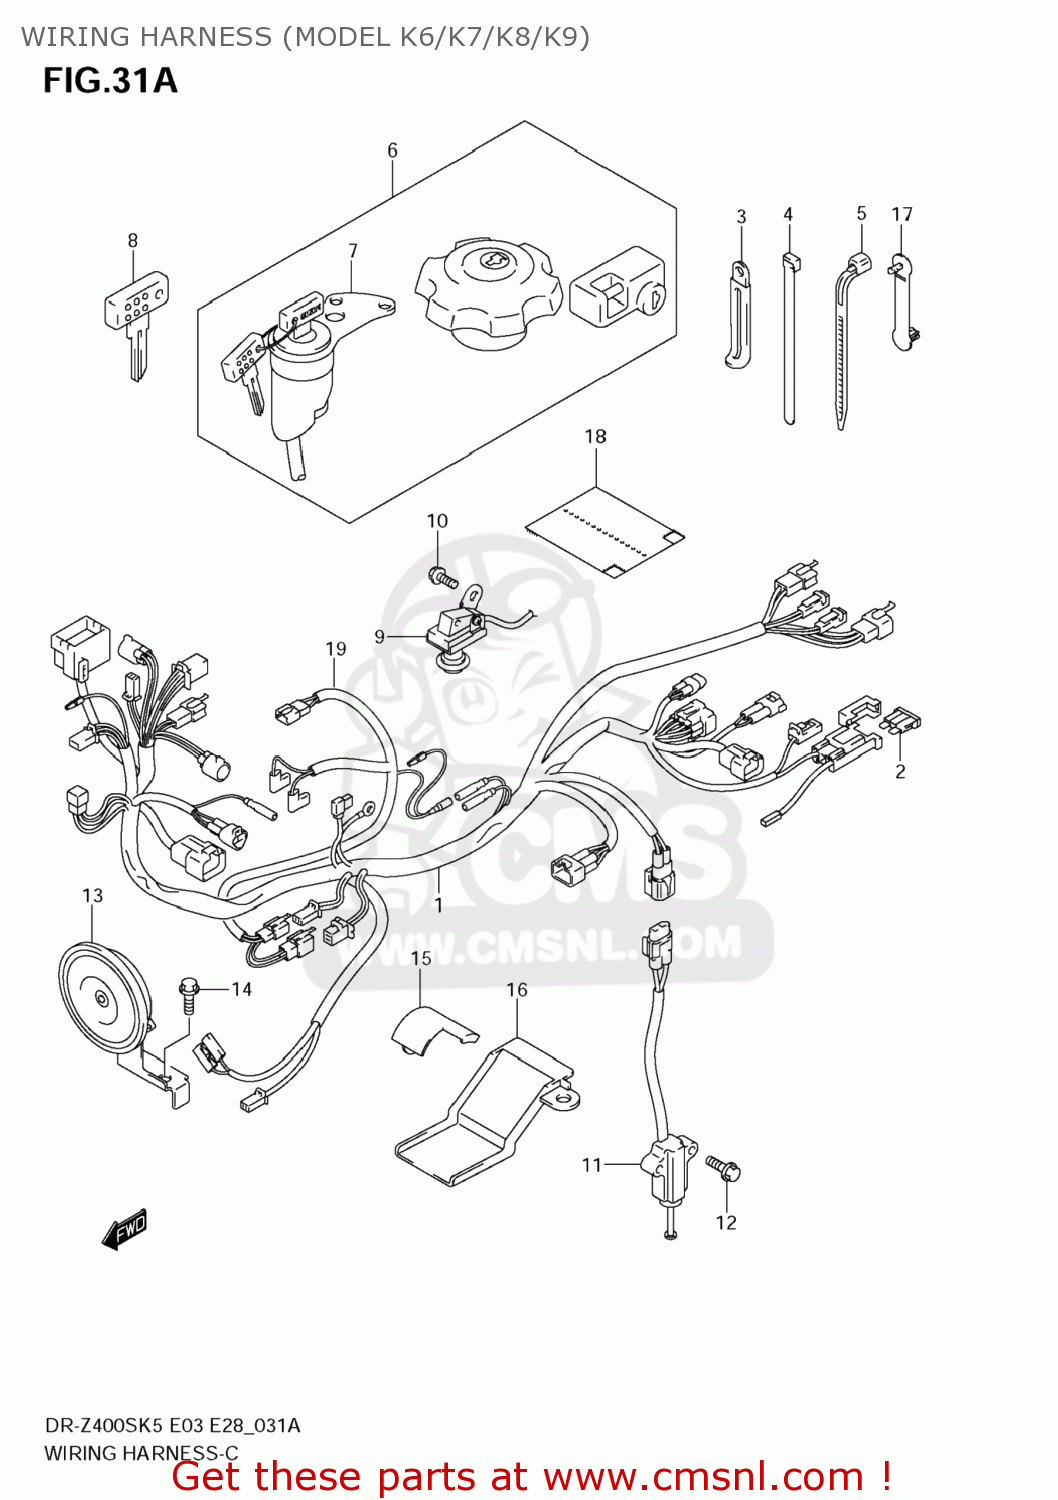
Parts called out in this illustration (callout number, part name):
1	HARNESS,WIRING
2	FUSE(20A)
3	CLAMP(L:45)
4	CLAMP(L:145)
5	CLAMP(L:125)
6	LOCK SET
7	SWITCH ASSY,IGNITION
8	KEY,BLANK(TYPE:C)
9	SWITCH ASSY
10	SCREW
11	SWITCH ASSY,SIDE STAND
12	BOLT
13	HORN ASSEMBLY
14	BOLT
15	PROTECTOR,WIRING HARNESS
16	PROTECTOR,WIRING HARNESS
17	CLAMP(L:63)
18	COVER,WIRING HARNESS
19	WIRE,CARB HEATER
